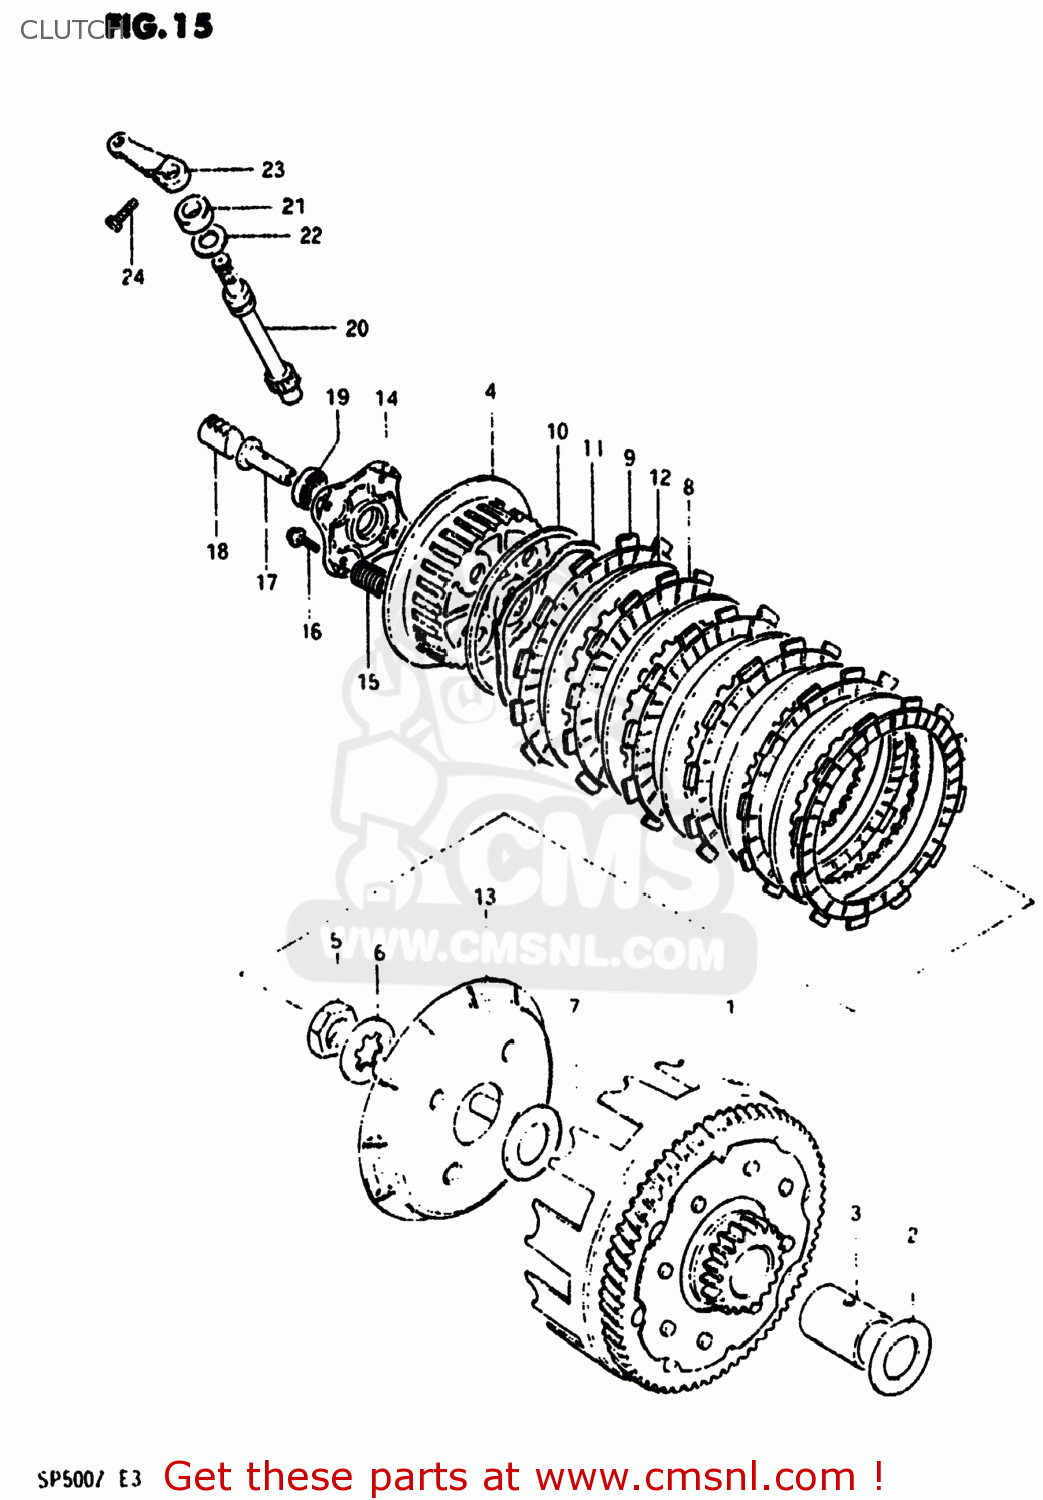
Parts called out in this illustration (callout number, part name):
1	GEAR ASSEMBLY,PRIMARY DRIVE
2	WASHER
3	SPACER(22X28X32.5)
4	HUB,CLUTCH SLEEVE
5	NUT
6	WASHER,LOCK
7	WASHER
8	PLATE,CLUTCH DRIVE (NAS)
9	PLATE,CLUTCH DRIVE
10	SEAT,WAVE WASHER(T:1.4)
11	WASHER
12	PLATE,CLUTCH DRIVEN
13	DISC,CLUTCH PRESSURE
14	PLATE,RELEASE
15	SPRING
16	BOLT,REAR
17	PIECE,CLUTCH PUSH
18	RACK,CLUTCH RELEASE
19	BEARING
20	PINION,CLUTCH RELEASE
21	OIL SEAL
22	WASHER (14.2X22X1)
23	ARM,CLUTCH RELEASE
24	BOLT
